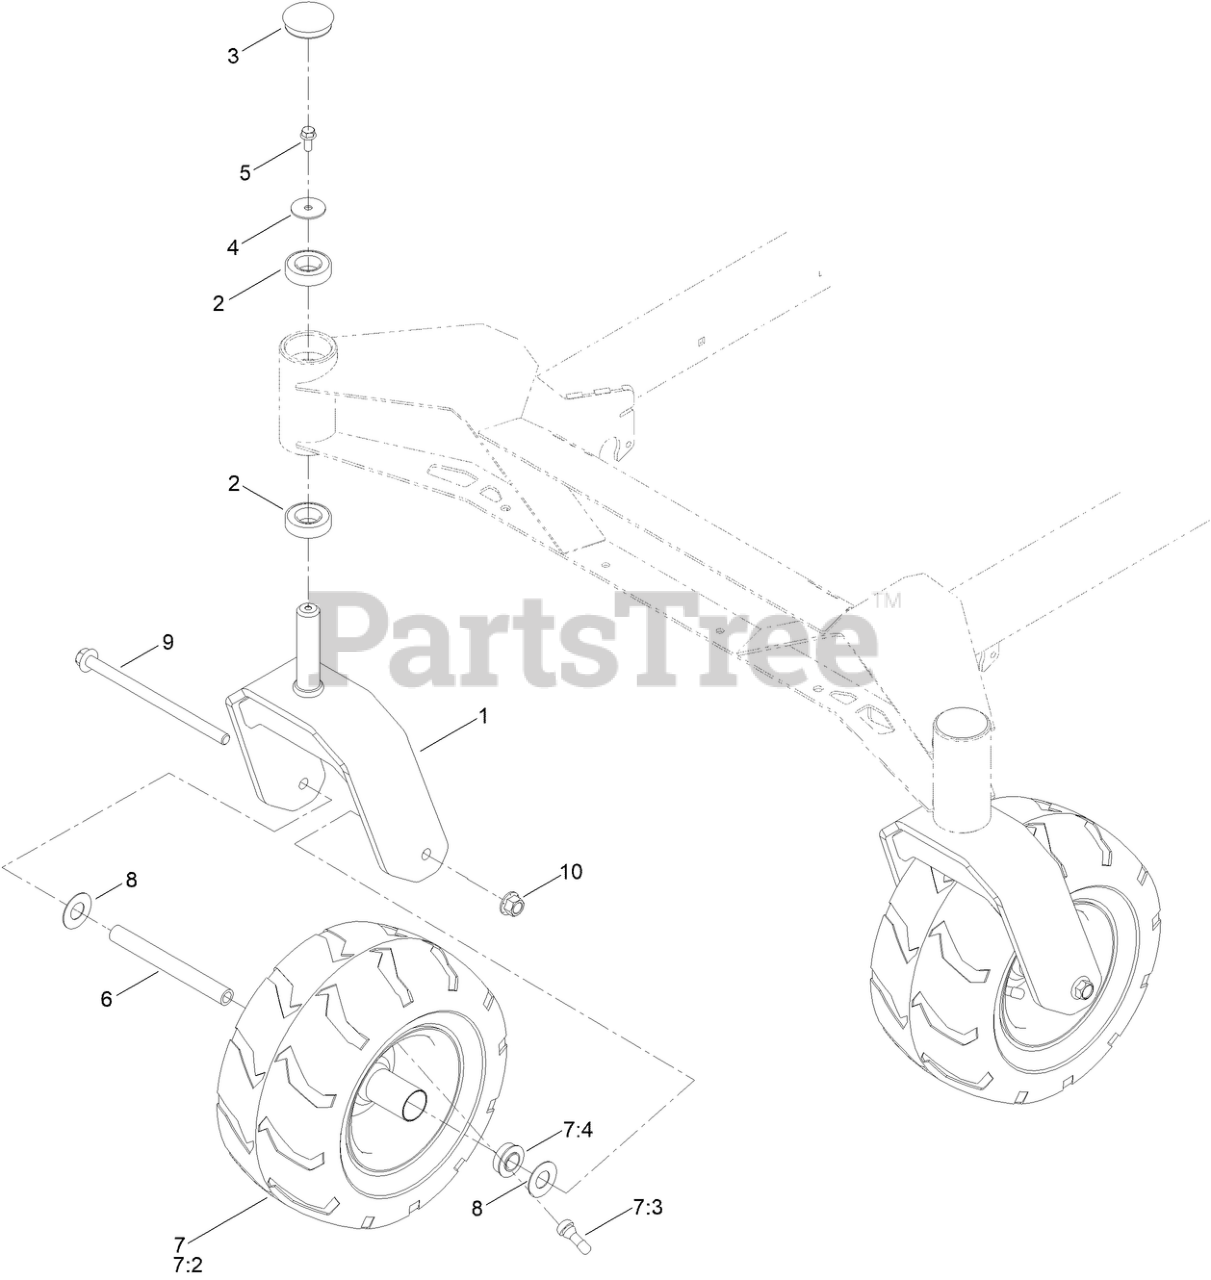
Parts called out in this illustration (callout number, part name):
1	CASTOR FORK
2	BEARING-BALL
3	CAP,GREASE
4	WASHER-FLAT
5	SCREW-HHF
6	SPANNER-WHEEL
7	TIRE AND WHEEL ASM
7:2	TIRE 13X6.5-6, TREADED
7:4	BEARING
8	WASHER
9	SCREW-HHF
10	NUT-HF
